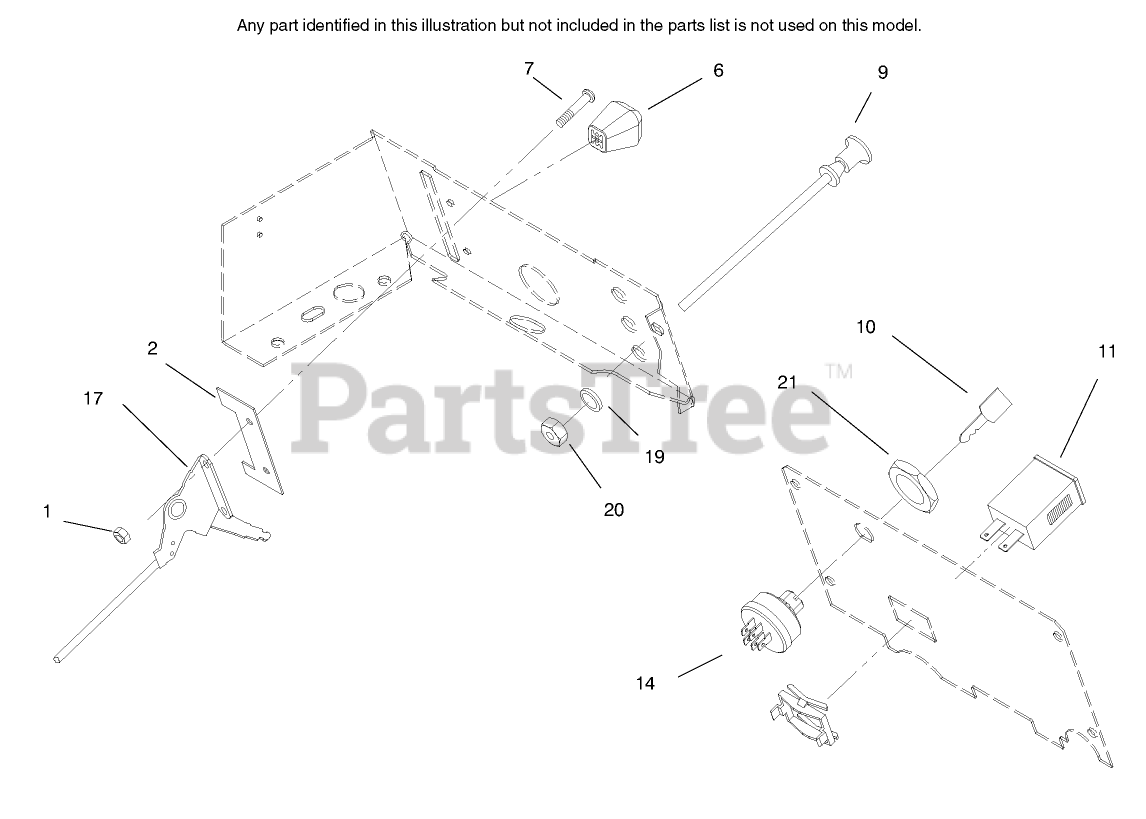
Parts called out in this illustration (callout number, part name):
7	SCREW-PPH
9	CHOKE CONTROL ASM
10	KEY-IGNITION
11	HOURMETER
14	SWITCH-IGNITION
17	THROTTLE CONTROL ASM
19	WASHER-FLAT
20	NUT-HEX PALNUT
